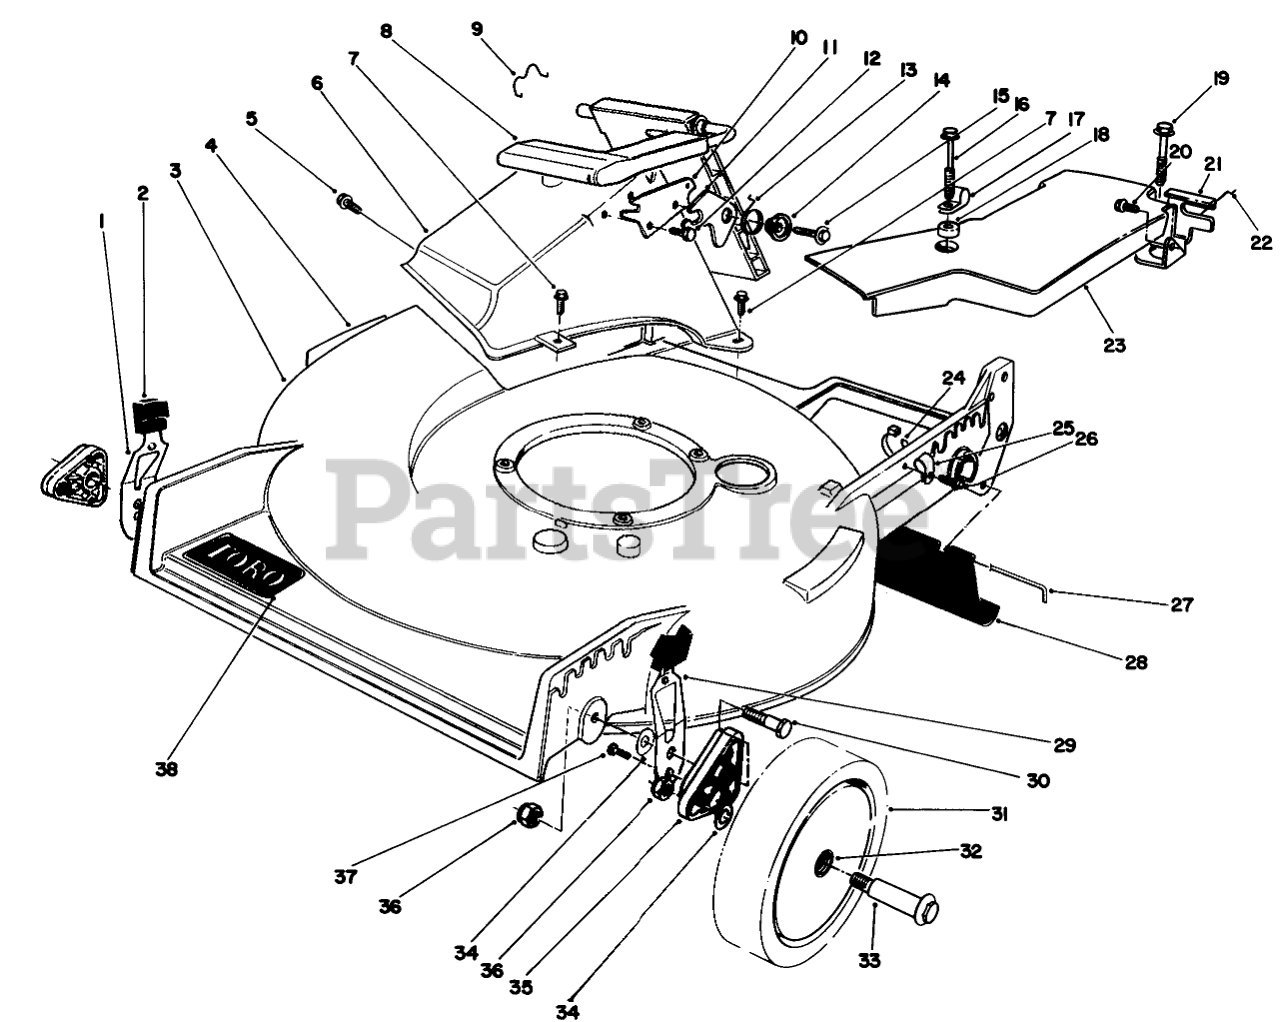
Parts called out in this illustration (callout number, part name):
1	RH SPRING ARM ASSEMBLY
2	KNOB-ARM
3	Housing (Incl. Ref. #4 & 38)
4	DECAL-DANGER
5	SCREW AND WASHER ASM
6	Tunnel Discharge
7	SCREW-HWH
8	Discharge Door Assembly
9	DOOR RET SPRING
10	DOOR LATCH PLATE
11	Latch-Door
12	SCREW-PLASTITE
13	TORSION SPRING
14	Latch Spacer
15	SCREW-HWH
16	SCREW-SPECIAL
17	CLAMP-CABLE
18	WASHER
19	SCREW-HHFTF
20	SCREW-HWHTF
21	Bracket-Traction Adj.
22	RETAINER-CABLE
23	Cover-Belt
24	TIE-CABLE
25	CLAMP-CABLE
26	SCREW
27	ROD-SHIELD
28	SHIELD-TRAILING
29	LH SPRING ARM ASSEMBLY
30	SCREW-SHOULDER
31	Wheel & Tire Assembly (Incl. Ref. #32)
32	BUSHING
33	WHEEL BOLT
34	WASHER
35	ARM-PIVOT, FRONT
36	Nut
37	SCREW-HWH
38	DECAL
